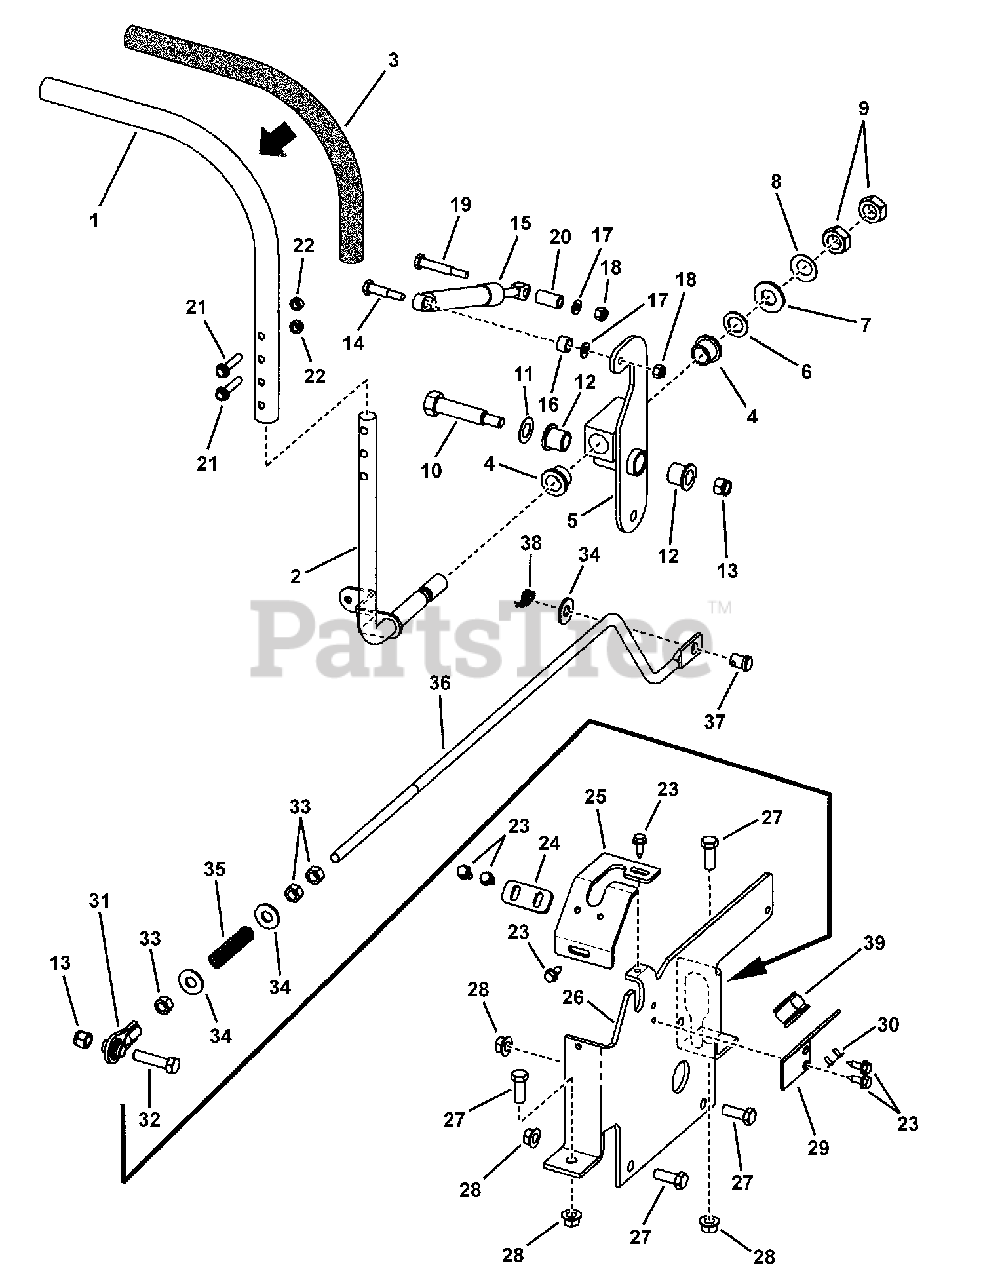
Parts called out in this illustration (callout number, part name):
1	HANDLE
2	WELDMENT, LH Control Arm (5/8" dia. Rod)
3	FOAM GRIP, Handle
4	BUSHING, Bronze, 5/8 x 5/8"
5	WELDMENT, Control Arm, LH
6	WASHER, 5/8 ID x 1.00 OD x .065 Nylon
7	WASHER, 5/8" Flat SAE
8	WASHER, .64 x 1.12 x .028 Beveled
9	NUT, 5/8-18 Hex Jam
10	SHOULDER BOLT, 3/8-16
11	THRUST WASHER, .562 ID x 1.000 OD x .030/.032 Thick
12	FLANGE BEARING, 9/16 I.D. P.M.
13	NUT, 3/8-16 Hex Nyloc
14	SHOULDER BOLT, 5/16 x 1/4-20
15	DAMPENER, Hydraulic
16	SPACER, 9/16 OD x 12GA x .325
18	NUT, 1/4-20 Hex Nyloc
19	SHOULDER BOLT, 5/16 x 1/4-20
0020	SUPPORT, Cargo Box, RH
20	SPACER, 9/16 OD x 12GA x .899
21	SCREW, 1/4-20 x 1-1/4" Hex Head Cap, GR 5
22	NUT 1/4-20 Hex Center Lock, GR 5 YZ
23	SCREW, 1/4-20 x 3/4" Hex Washer Self-Tap
24	PLATE, Fwd/Rev Adjust
25	TRACK, Control Stick, L.H.
26	CONTROL BRACKET, LH
27	SCREW, 3/8-16 x 1" Hex Head Cap, GR 5, YZ
28	NUT, 3/8-16 Hex Flange Lock
29	BRACKET, Rod Holder, RZT
30	POP RIVET, 1/8 x 3/8"
31	ROD END
32	SCREW, 3/8-16 x 1-1/2" Hex Head Cap, GR 5
33	NUT, 3/8-24 Hex, GR B, YZ
34	WASHER, 7/16" Flat
35	SPRING, Compression (Brake)
36	ROD, Link Fwd./Rev. (3/8-24 thread)
37	CLEVIS PIN, 7/16 x 1"
38	COTTER PIN, 1/2 Self Locking, YZ
39	CLIP, Spring
